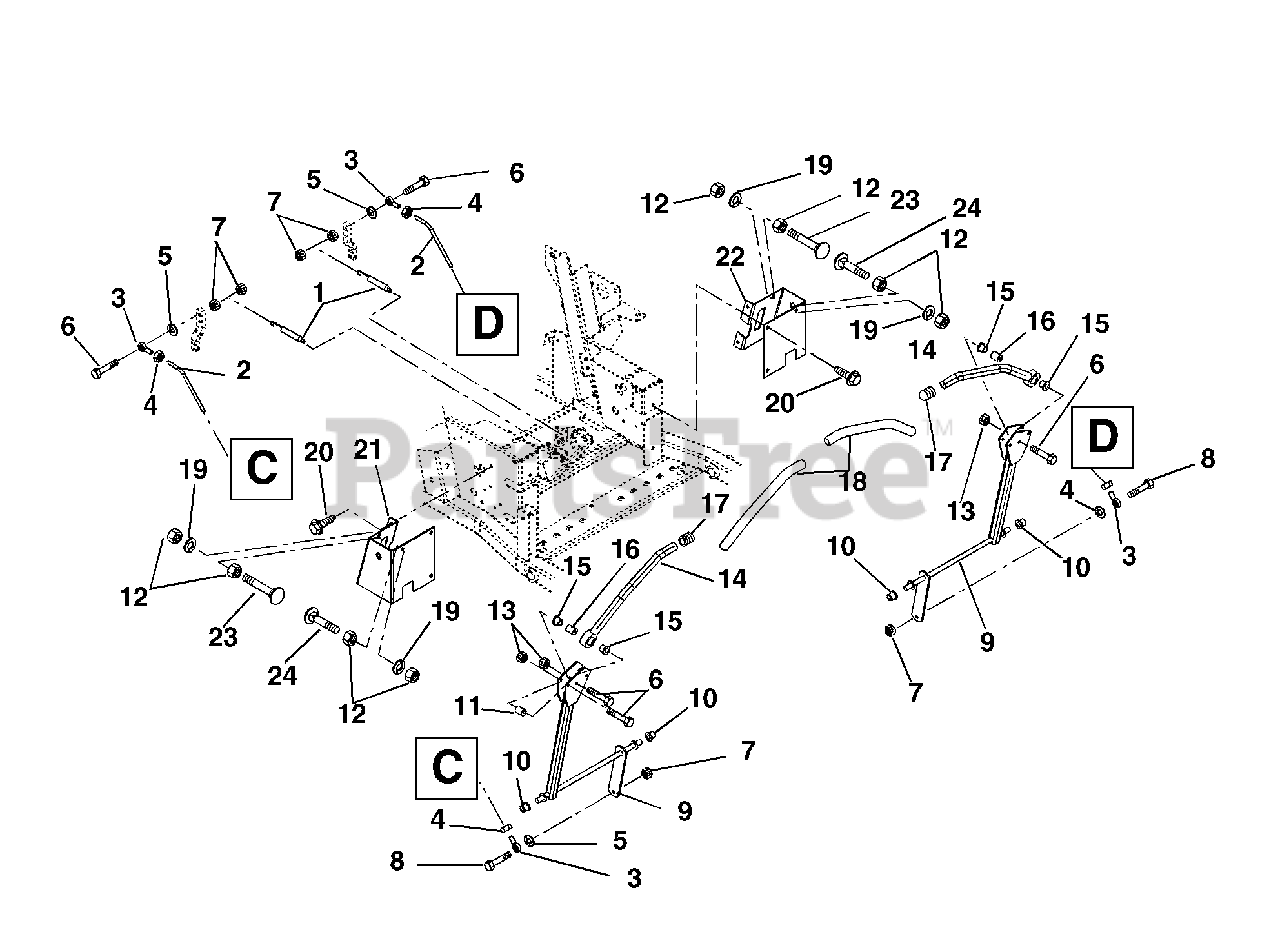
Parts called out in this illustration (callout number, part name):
1	Spring-Tension .062 x .56 x 8.0
2	Rod-Steering Adjustment
3	Rod End .312 Right-Hand-Female
4	Nut-Jam .31-24
5	Washer-Locking .31 x .078
6	Bolt-Hex .31-18 x 1.75 Grade 5
7	Nut-Locking-Center .31-18
8	Bolt-Hex .31-18 x 1.50 Grade 5
9	Rod-Steering
10	Bushing-Flange .515 x .750 x .745 x 1.00
11	Eccentric
12	Nut-Hex .38-16
13	Nut-Locking-Center .31-18
14	Handle Weldment Left-Hand
14	Handle Weldment Right-Hand
15	Bushing-Flange-Nylon .762 x 1.48 x .44
17	Caplug- Handlebar
18	Grip-Handlebar
19	Washer-Locking .38 x .094
20	Screw-Tapping .38-16 x .75 Hex Washer Head
21	Mount-Steering Rod-Right Hand
22	Mount-Steering Rod-Left Hand
23	Bolt-Round Head Square Neck .38-16 x 2.00
24	Bolt-Round Head Square Neck .38-16 x 1.50
